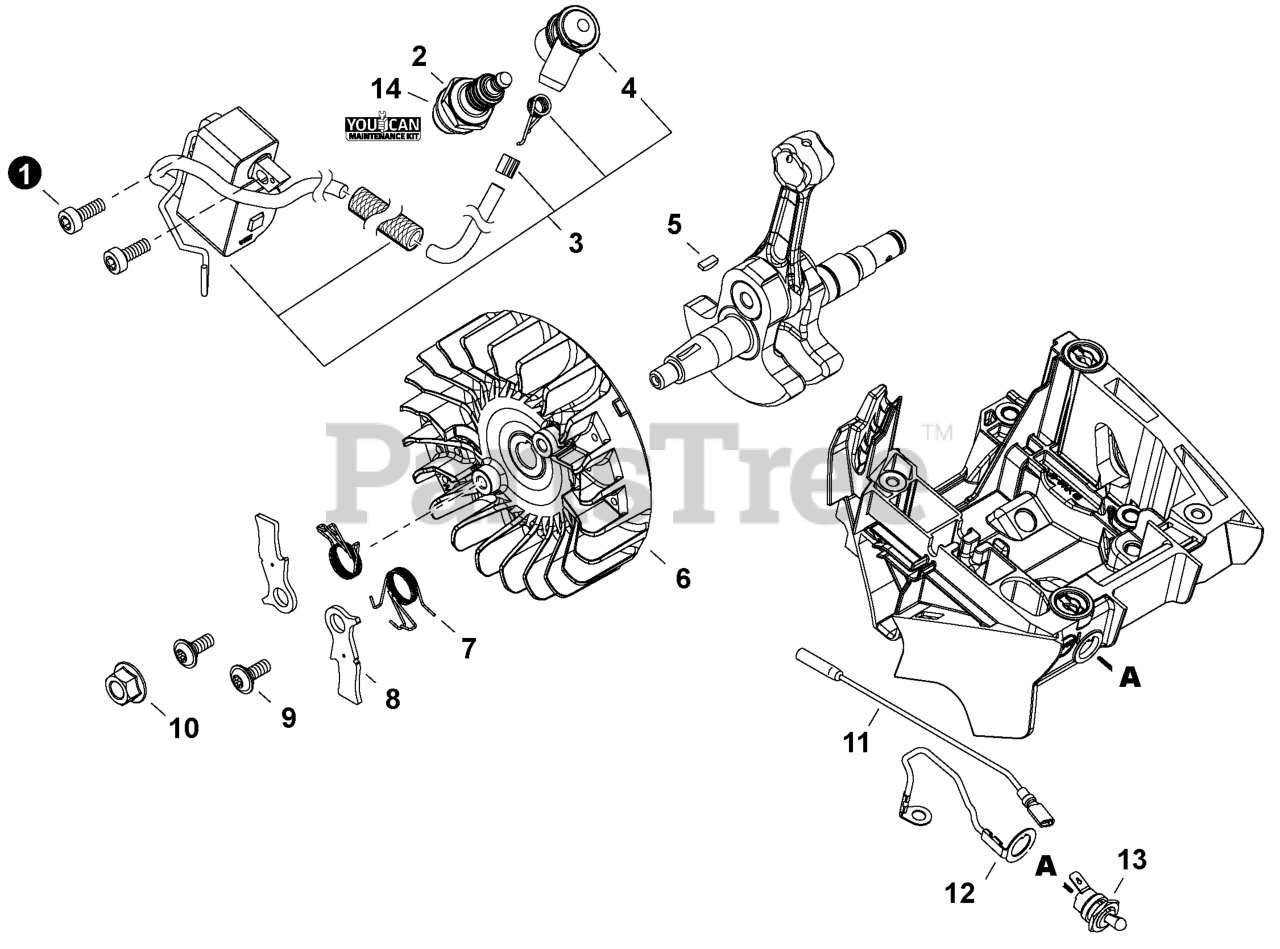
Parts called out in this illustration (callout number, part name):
1	BOLT, TORX 5x16
2	SPARK PLUG - BPMR8Y-5
3	COIL ASSY, IGNITION
4	CAP, SPARK PLUG
5	KEY, WOODRUFF
6	FLYWHEEL
7	SPRING, TORSION
9	BOLT 5x11
10	NUT, FLANGE M8
13	SWITCH, ON-OFF
14	TUNE-UP KIT - YOUCANT
